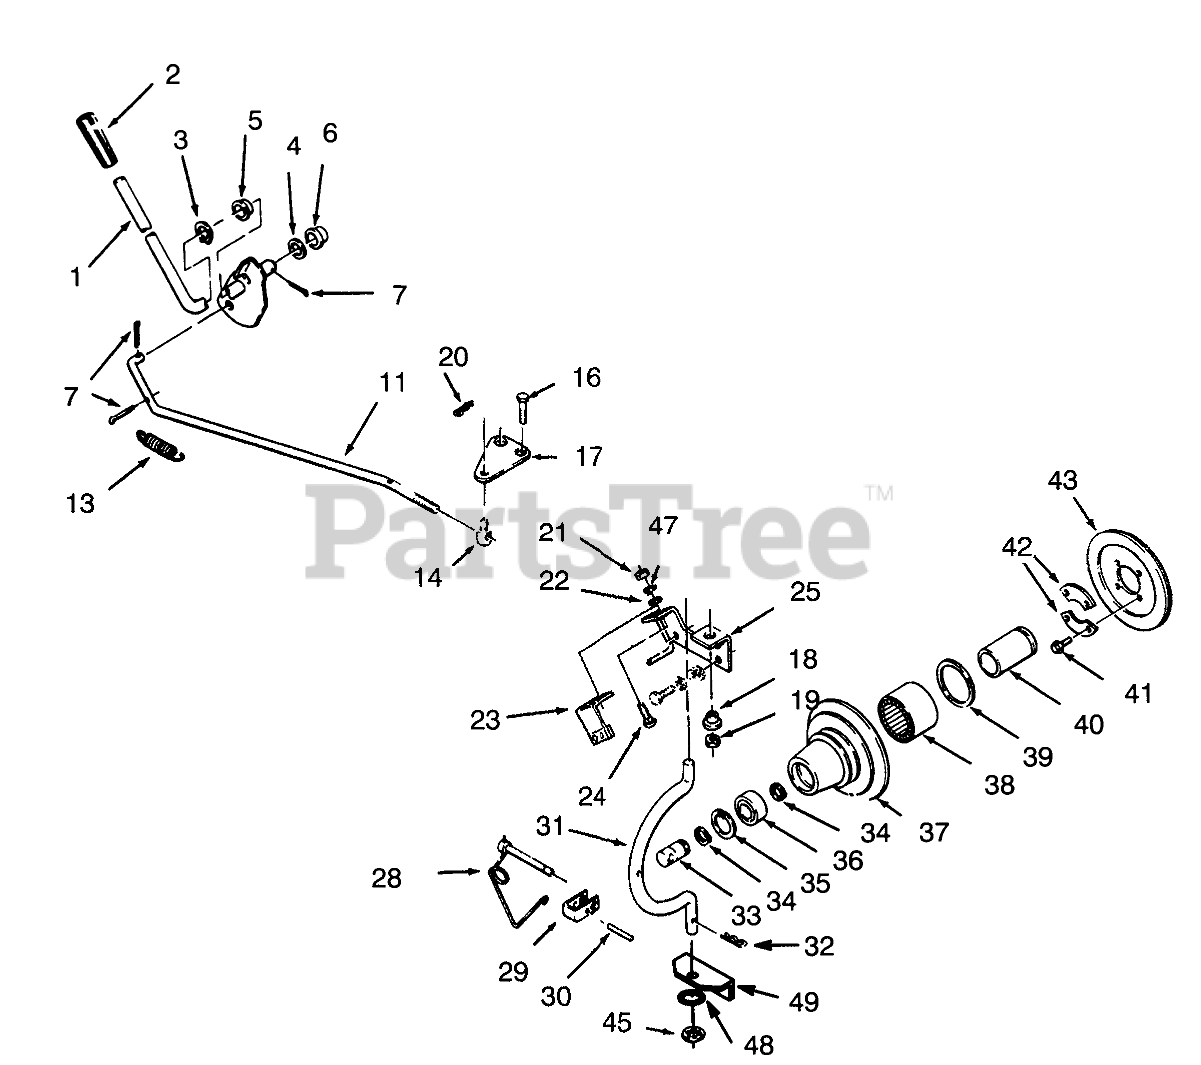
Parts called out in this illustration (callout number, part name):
1	ASSY PTO CLUTCH LEVE
2	GRIP
3	RING-EXT GRIP
4	SHIM-WASHER
5	BUSHING-NYLINER
6	NYLINER BUSHING
7	PIN-COTTER
11	ROD-PTO CLUTCH
13	SPRING
14	TRUNNION
16	SCREW-HH
17	PLATE
18	SPACER-LIFT LINK
19	NUT-LOCK, NI
20	Hairpin Cotter
21	NUT-JAM
22	WASHER-FLAT
23	ASM-Bracket
24	SCREW-CARR
25	Bracket
28	LOCKING PIN ASM
29	CLEVIS
31	ROD-HOUSING
32	Hairpin
33	SHAFT-PTO
34	Ring-Snap
35	RING-RETAINING
36	BEARING-BALL
37	Housing-Clutch
38	Seal
39	SEAL-OIL
40	RACE-BEARING
41	SCREW-HH
42	RETAINER
43	Facing-Clutch
45	RING-REINFORCED CIRC
47	WASHER-LOCK
48	WASHER-FLAT
49	Axle
